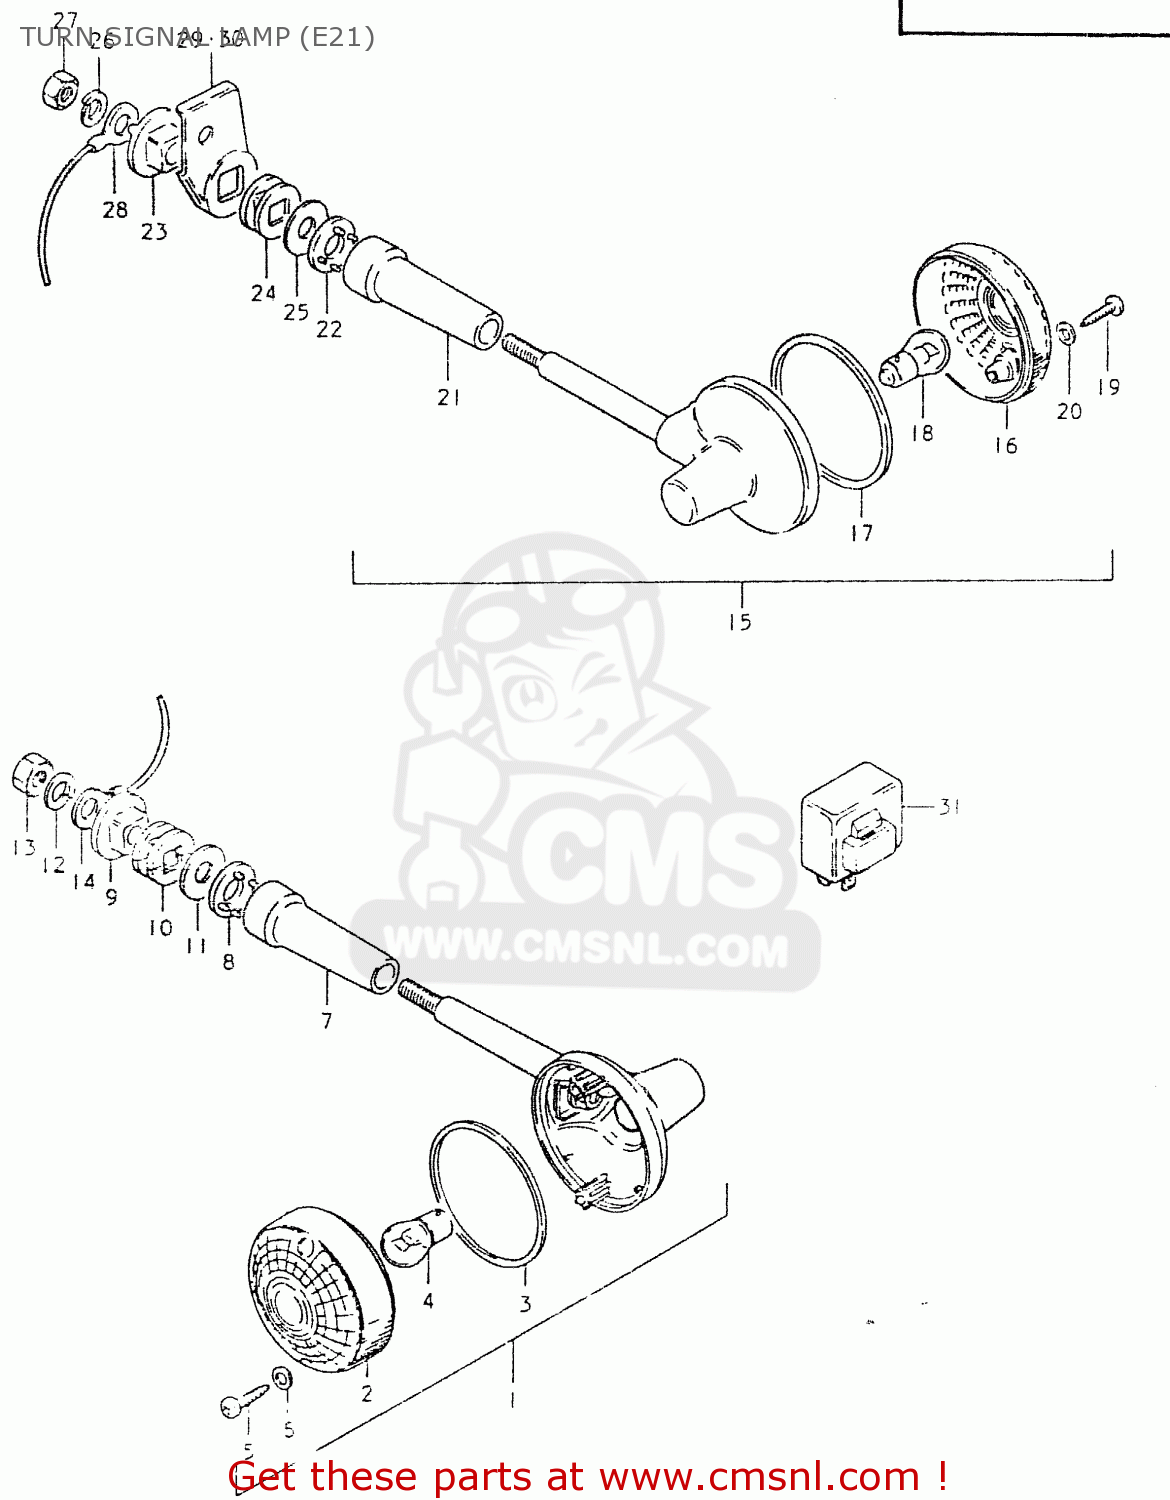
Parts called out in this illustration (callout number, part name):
1	LAMP ASSY FRON
2	LENS
3	GASKET (NAS)
4	BULB 12V 21W
5	SCREW
6	GASKET (NAS)
7	COVER,STAY
8	SPACER
9	SPACER,TURN SIGNAL LAMP
10	CUSHION
11	WASHER (10.5X30X2.3)
12	LOCK WASHER
13	NUT
14	WIRE
15	LAMP, REAR TURN SIGNAL
16	LENS
17	GASKET (NAS)
18	BULB 12V 21W
19	SCREW
20	GASKET (NAS)
21	COVER,STAY
22	SPACER
23	SPACER,TURN SIGNAL LAMP
24	CUSHION
25	WASHER (10.5X30X2.3)
26	LOCK WASHER
27	NUT
28	WIRE
29	BRACKET,RR TURNSIGNAL LAMP,R
30	BRACKET,RR TURNSIGNAL LAMP,L
31	RELAY,TURN SIGNAL
